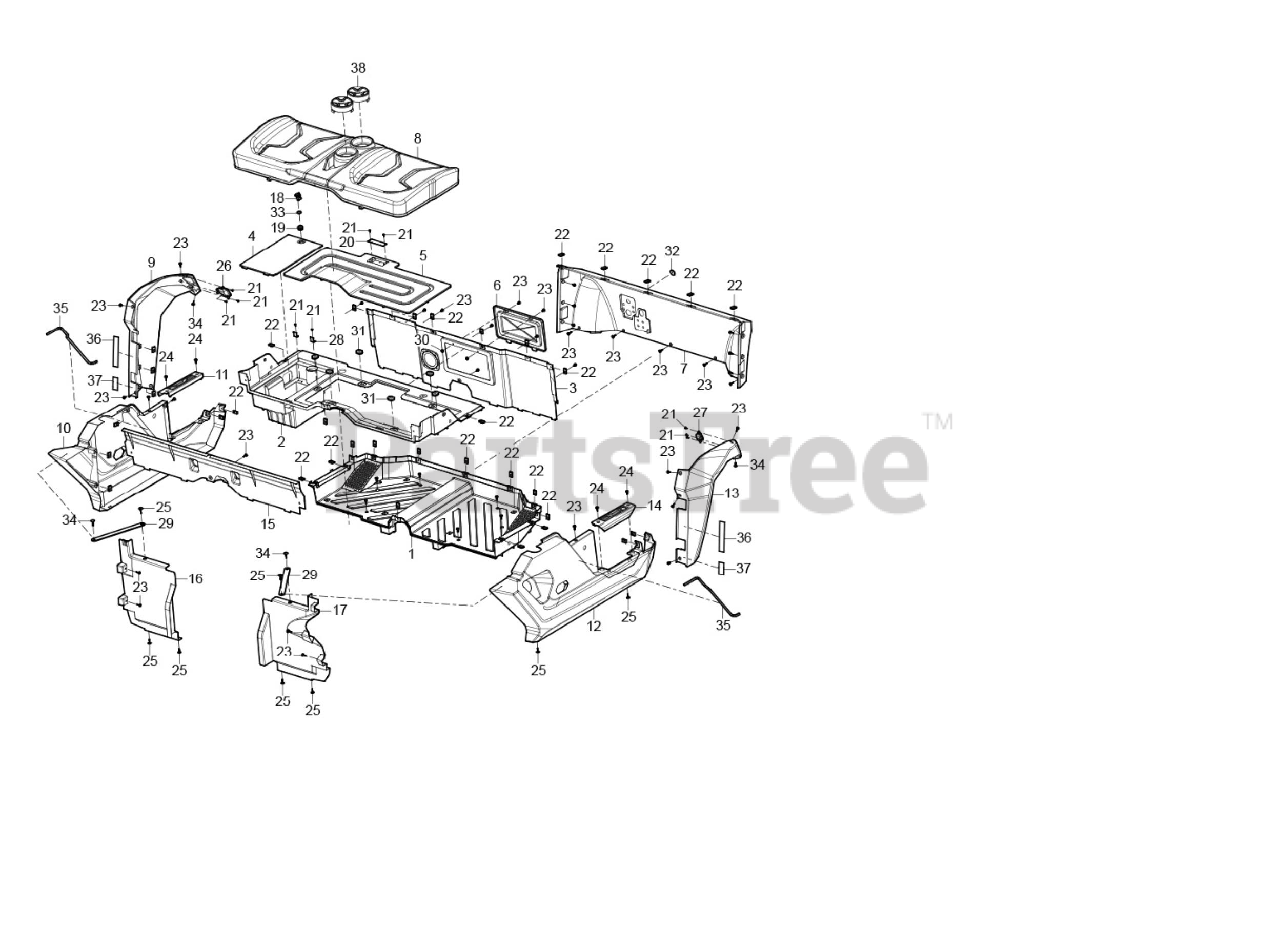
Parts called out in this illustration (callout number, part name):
2	SEATING SUPPORT ?
3	SEATING SUPPORTII
4	COVER - BATTERY
5	COVER - ENGINE
6	COVER - BATTERY BOx
7	FRONT PANEL FOOT REST
8	BOTTOM SEAT KIT
9	SIDE PANEL - FRONT LEFT
10	SIDE PANEL - MIDDLE LEFT
11	SIDE PROTECTOR - LEFT
12	SIDE PANEL - MIDDLE RIGHT
13	SIDE PANEL - FRONT RIGHT
14	SIDE PROTECTOR - RIGHT
15	SEATING PROTECTOR
16	REAR MUDGUARD II
17	REAR FENDER
18	LOCK - BATTERY BOx COVER
19	RUBBER WASHER
20	LOCK - ENGINE COVER
21	SCREW - CROSS HEAD SELF DRILLING ST3.9x10
22	CLAMP NUT M6x6
23	Socket Hex Flat Head Bolt M6x16
24	BOLT HExAGON SOCKET FANGLE M6x20
25	Cross Large Plate Head Screw M6x16
26	TURN LIGHT - FRONT LEFT
27	TURN LIGHT - FRONT RIGHT
28	STARTER RELAY BRACKET PLATED
29	SIDE PLATE SUPPORT ?
30	HExAGON FLANGE HEAD NUT M6
31	RUBBER WASHER 8x17
32	BRAKE PEDAL DUST PAD
33	Flat Washer 15x 22x1.5
34	HExAGON SOCKET HEAD CAP SCREWS M6x16
35	DOOR SEAL 1
36	DOOR SEAL 2
37	DOOR SEAL 3
38	CUP HOLDER
